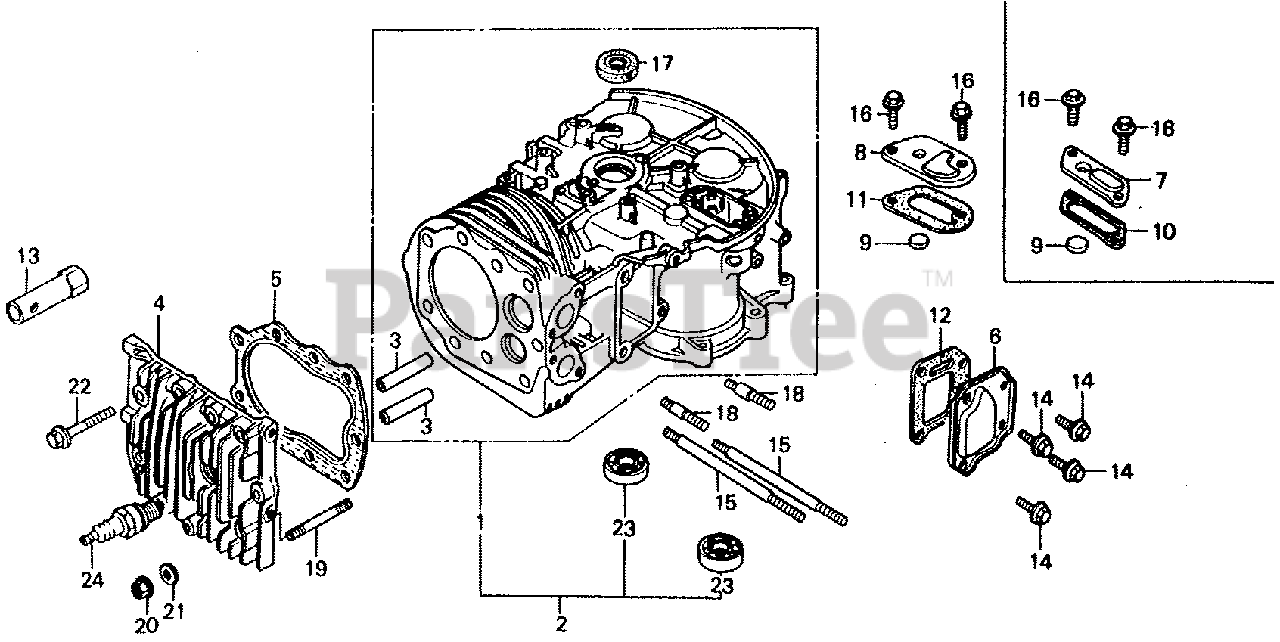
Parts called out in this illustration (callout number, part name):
1	CYLINDER ASSY.
3	GUIDE, VALVE
4	CYLINDER HEAD
5	GASKET, CYLINDER HEAD
6	COVER, TAPPET
7	CAP, BREATHER CHAMBER
9	VALVE, BREATHER
10	GASKET, BREATHER CAP
12	GASKET, TAPPET COVER
13	WRENCH, SPARK PLUG
14	BOLT, FLANGE (6X12) (CT200)
15	BOLT, STUD (8X125) (NOT AVAILABLE)
16	BOLT, FLANGE (6X16)
17	OIL SEAL (30X46X8)
18	BOLT, STUD (8X28)
22	BOLT, FLANGE (10X55)
24	SPARK PLUG (BM6A) (NGK)
24	SPARK PLUG (BMR6A) (NGK)
24	SPARK PLUG (BPM6A-10) (NGK)
24	SPARK PLUG (BPMR6A-10) (NGK)
